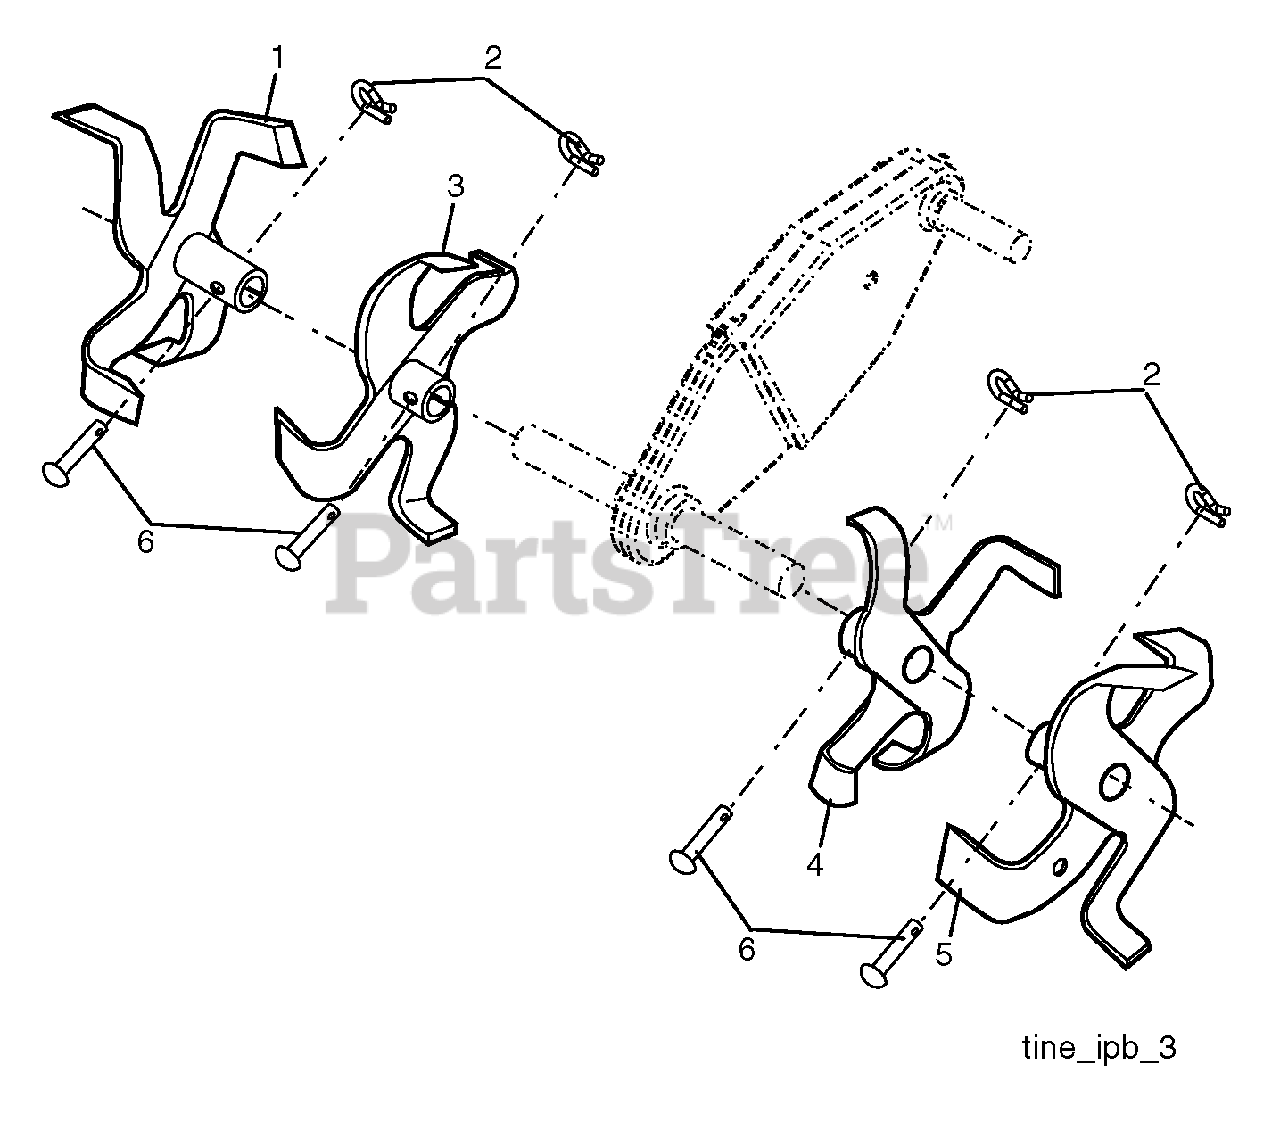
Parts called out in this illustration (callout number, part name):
1	TINE.ASM.OUTER.RH.13.PNT
2	SPRING RETAINER
3	TINE.ASM.INNER.RH.13.PNT
4	TINE.ASM.INNER.LH.13.PNT
5	TINE.ASM.OUTER.LH.13.PNT.479
6	RIVET.PAN.HD.DRILLED
